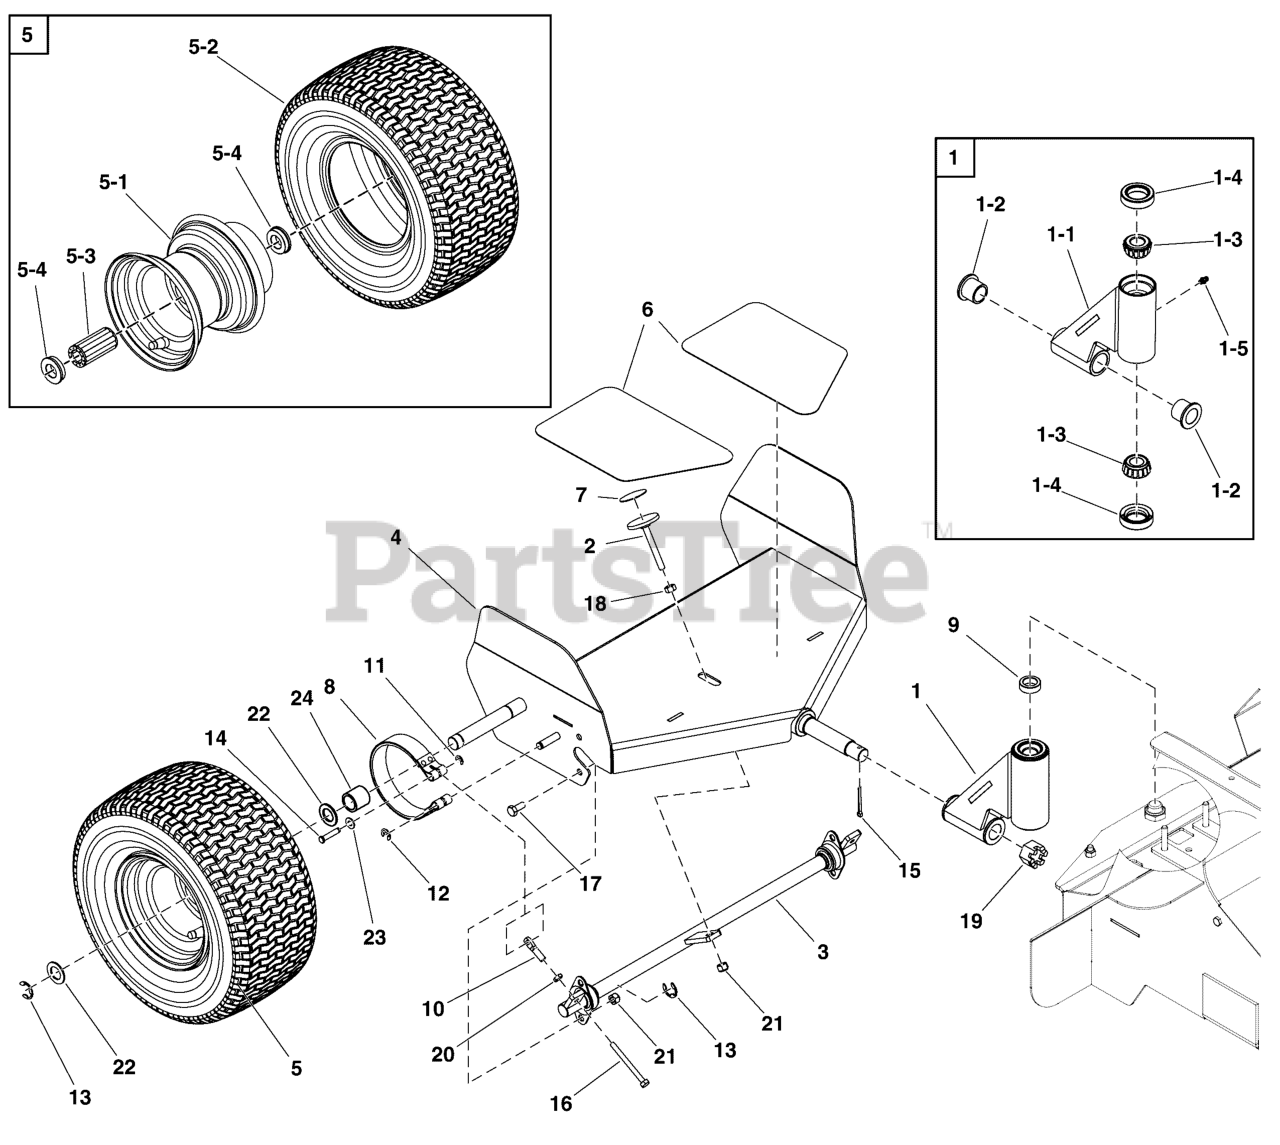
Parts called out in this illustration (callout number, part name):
1-1	WELD, HINGE SULKY
1-2	BUSHING, FLANGE 7/8 ID X 1 1/8 OD X 1 LG
1-3	CONE, TPR-ROL Ø.750" ID X Ø1.521" OD x .655" TH
1-4	SEAL, 1.125" BORE X 1.784" OD X 0.469 THK
1-5	ZERK, GREASE .250"-28 SS
2	WELD, BRAKE PEDAL
3	BRAKE SHAFT ASSY, ROVER (S0301)
4	WELD, SULKY FRAME
5	ASM, WHEEL & TIRE 13" X 6.50" - 6 TURF
5-1	WHEEL FOR 13X6.50-6 TIRE ASSM
5-2	TIRE, 13 X 6.50 - 6
5-3	BEARING, ROLLER (C0147)
5-4	RETAINER, BEARING (C0148)
6	PADS, NON-SLIP PLATFORM
7	PAD, NON-SLIP ROUND BRAKE
8	BRAKE, BAND 4.00 INCH
9	SPCR-SS, 303 .750" X 1.125" X .375
10	NUT-EYE .250" 20 X 1.500 OAL ZP
11	E-RING, 0.250" SHAFT SSPH
12	E-RING, 0.375" SHAFT YZ
13	E-RING, .750" SHAFT YZ
14	PIN, CVS .250" X 1.125" SS188
15	PIN-CTR, .156" X 1.500" SS188
16	SCR-CAP, HEX .250"-20 X 2.750" SS188
17	SCR-CAP, HEX .3125"-18 X .750" SS188
18	NUT-HEX, .3125"-18 SS188
19	NUT-HEX, CSTL .750"-16 GR2 ZP
20	NUT-HEX, JAM .250"-20 SS188
21	NUT-HEX-NYLK, 0.3125"-18 SS188
22	WSHR-STL, FLT .750"X1.250" X .075" MAB ZP
23	WSHR-STL, FLT .281" X .625" X .050" IS SS188
24	KIT, SULKY WHEEL SPACER
